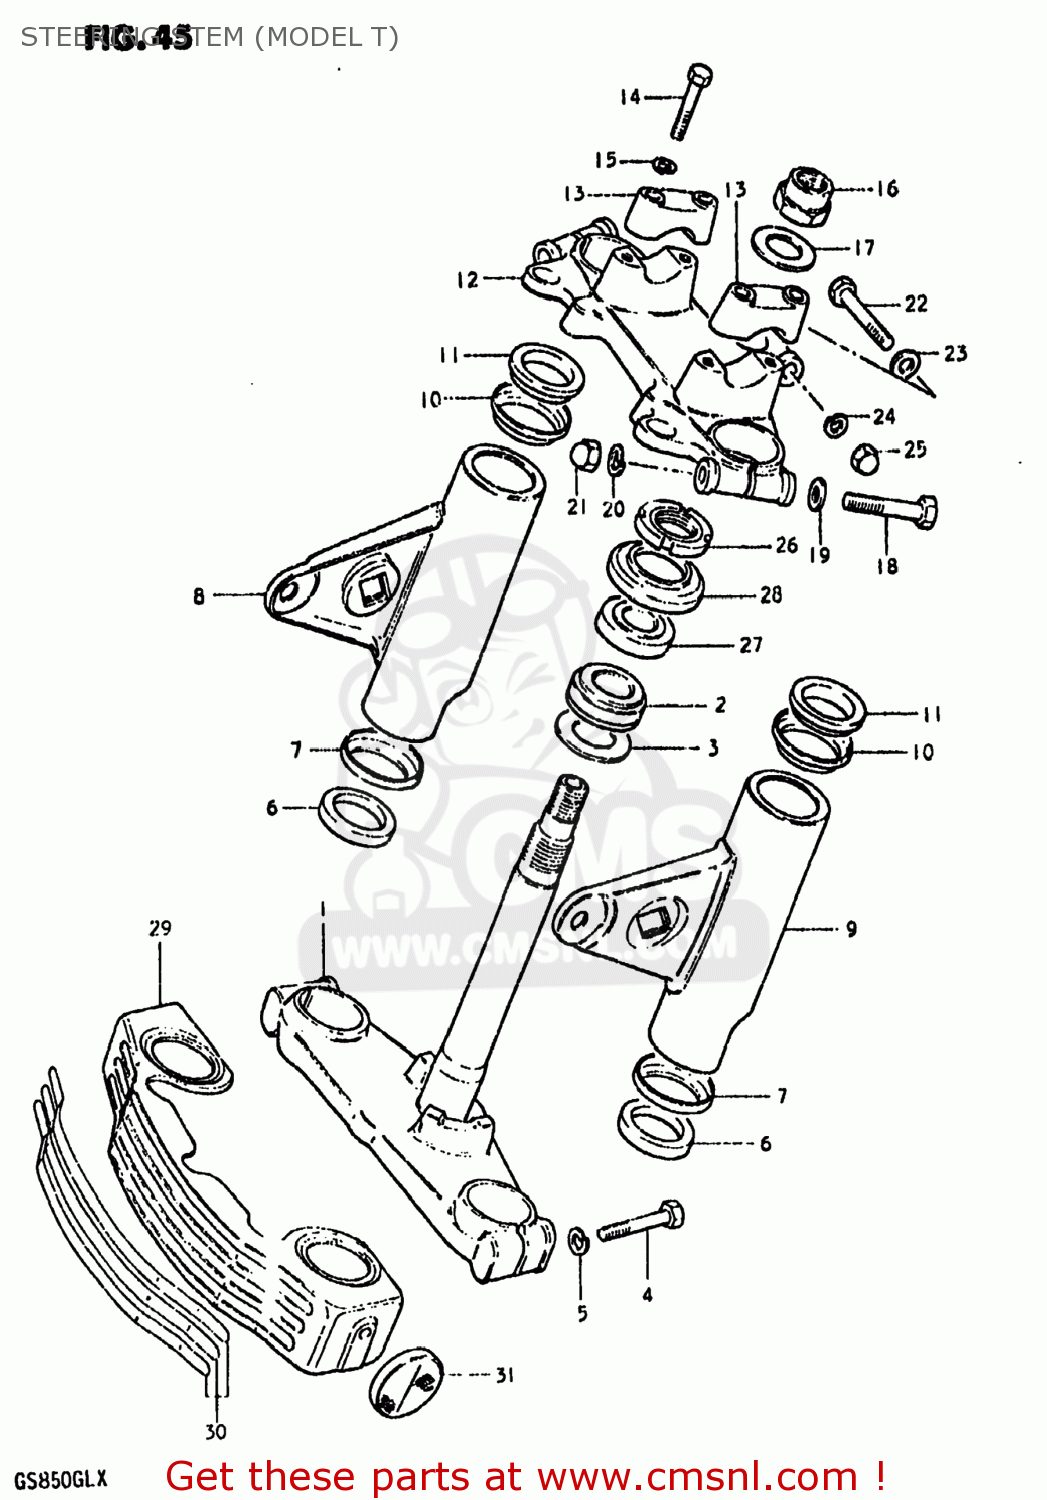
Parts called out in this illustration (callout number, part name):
1	STEM. STEERING
2	BEARING
3	WASHER,THRUST
4	BOLT
5	LOCK WASHER
6	CUSHION,HEADLAMP BRACKET
7	SEAT,HEAD LAMP BRACKET
8	BRACKET,HEADLAMP,RIGHT
9	BRACKET,HEADLAMP,LEFT
11	CUSHION,HEADLAMP BRACKET
12	HEAD,STEERING STEM
13	HOLDER,HANDLE(BLACK)
14	BOLT
15	LOCK WASHER
16	NUT,FR FORK UPR BRACKET
17	WASHER
18	BOLT 10X55
19	WASHER
20	LOCK WASHER
21	NUT 10MM
22	BOLT 8X50
23	WASHER
24	WASHER,LOCK,8.
25	NUT,M8X1.25X12
26	NUT,STEERING STEM(25X44X10)
27	TAPER,ROLLER BEARING
28	DUST SEAL,STEERING,UPPER
29	COVER,FRONT FORK
30	TAPE SET,FRONT FORK COVER
31	REFLEX REFLECTOR,RR
